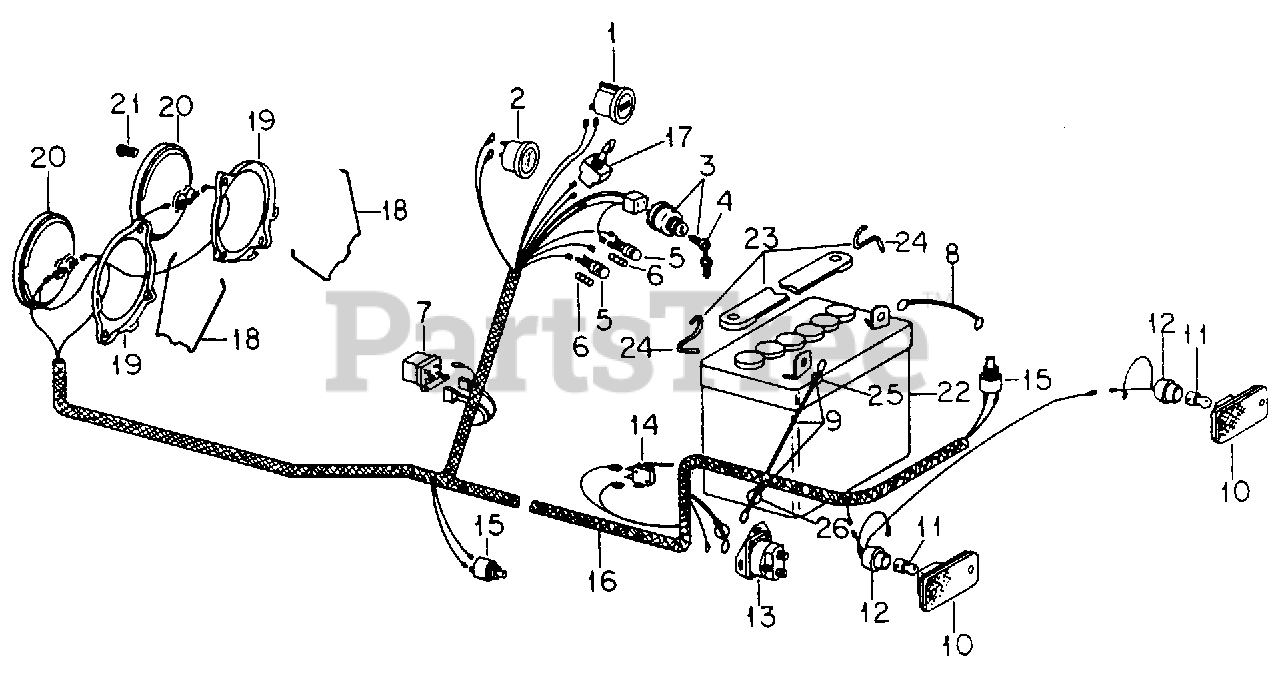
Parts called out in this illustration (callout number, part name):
1	Package, Hourmeter
2	Indicator, Charge
3	Switch, Magneto Ignition
4	Key, Ignition Switch
5	Holder, Fuse
6	Fuse, 15 Amp
7	Relay
8	Cable, Battery, Negative Terminal To Ground
9	Cable, Battery, Positive
10	Lens Assy, Taillight
11	Bulb, Taillight #194
12	Cable Assy, Taillight
13	Switch, Magnetic, Solenoid
14	Switch, Reverse Cut Out
15	Switch, Neutral Start
16	Harness Assy, Main Cable
17	Switch, PTO
18	Spring, Headlamp Retaining
19	Retainer, Headlamp
20	Light, Sealed Beam Head
21	Screw, Headlight
22	Battery, 12 Volt
23	Strap Assy, Battery
24	Hook, Battery Strap
25	Cover, Battery Terminal
26	Insulator, Terminal Boot
